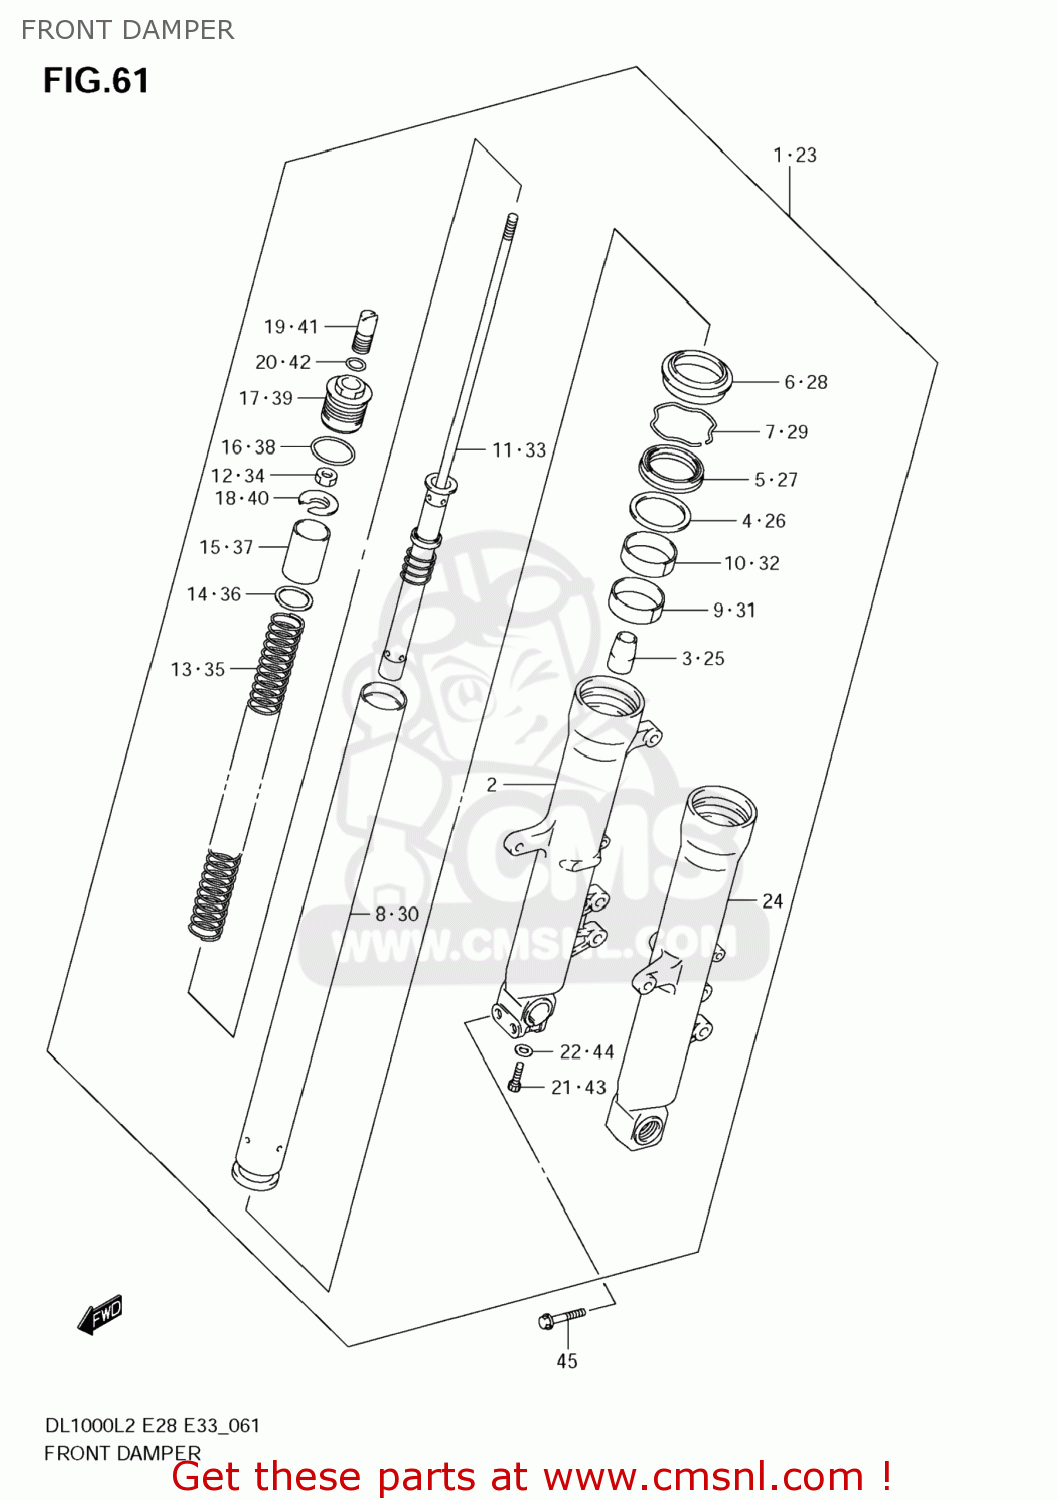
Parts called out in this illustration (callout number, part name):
1	DAMPER ASSY,FR FORK,R
2	TUBE,OUTER,R
3	PIECE,OIL LOCK
4	SPACER,SEAL
5	SEAL,OIL
6	SEAL,DUST
7	CIRCLIP,FORK OIL SEAL
8	TUBE,INNER
9	BUSH,SLIDE
10	BUSH,GUIDE
11	ROD,FR DAMPER
12	NUT
13	SPRING,FR
14	SEAT,SPRING LWR
15	COLLAR,SPRING(32.9X34X50)
16	O RING
17	BOLT,FORK
18	SEAT,SPRING UPR
19	ADJUSTER,SPRING
20	O RING(D:2.5,ID:13.8)
21	BOLT(8X27)
22	GASKET (NAS)
23	DAMPER ASSY,FR FORK,L
24	TUBE,OUTER,L
25	PIECE,OIL LOCK
26	SPACER,SEAL
27	SEAL,OIL
28	SEAL,DUST
29	CIRCLIP,FORK OIL SEAL
30	TUBE,INNER
31	BUSH,SLIDE
32	BUSH,GUIDE
33	ROD,FR DAMPER
34	NUT
35	SPRING,FR
36	SEAT,SPRING LWR
37	COLLAR,SPRING(32.9X34X50)
38	O RING
39	BOLT,FORK
40	SEAT,SPRING UPR
41	ADJUSTER,SPRING
42	O RING(D:2.5,ID:13.8)
43	BOLT(8X27)
44	GASKET (NAS)
45	BOLT
